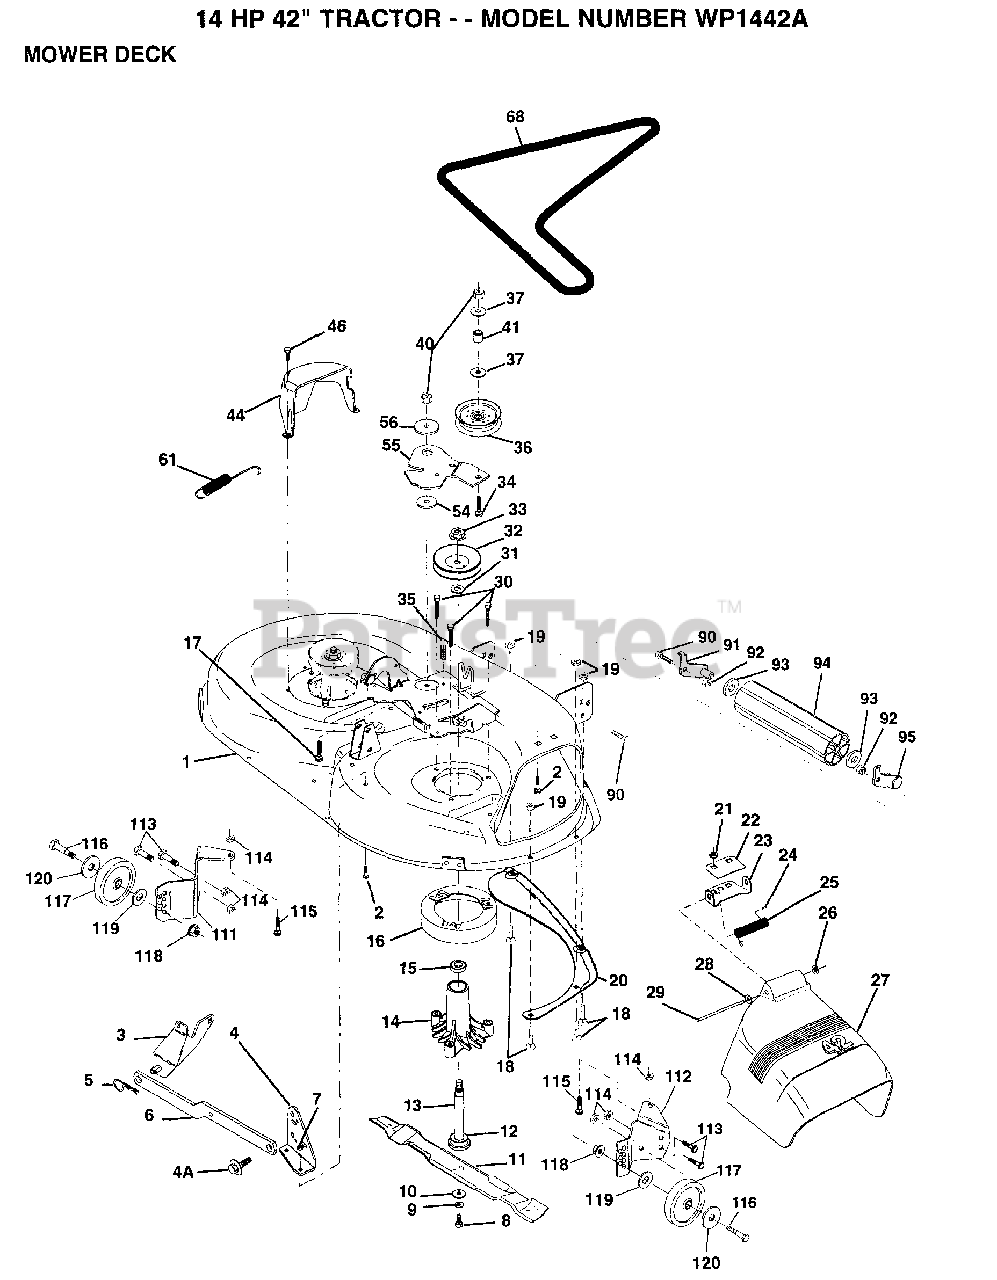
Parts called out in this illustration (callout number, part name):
2	BOLT
3	BRKT ASM SWAY BAR
4	BRKT DECK SW BAR
4A	BOLT SHD 5/16-18
7	NUT
8	BLADE BOLT
10	WASHER.HARD.BLADE
11	"BLADE.42"" MULCHER"
12	BEARING.BALL
14	HSG ASM MANDREL
15	BEARING
16	STRIPPER RND MWR
17	BOLT
18	BOLT
19	NUT
21	NUT
22	STIFFENER BRKT
23	DEFLECTOR BRKT
24	CAP-SLEEVE LT
25	SPRING TORSION
26	NUT PUSH M
27	DEFLECTOR.SHIELD
28	WASHER
29	HINGE ROD
31	WASHER
34	BOLT RDHD 3/8-16
35	XMAS TREE FASTNER
36	FLAT IDLER PULLEY
37	WASHER
40	NUT
44	GUARD MAND LH BLK
46	SCREW.1/4-20X5/8
54	HARDENED WASHER
56	SPACER RETAINER
61	SPRING.EXTENSION
68	BELT-V MWR 82.625
113	BOLT
116	BOLT M
117	WHEEL.GAGE.BLK.PL
118	LOCKNUT
119	WASHER
120	WASHER
